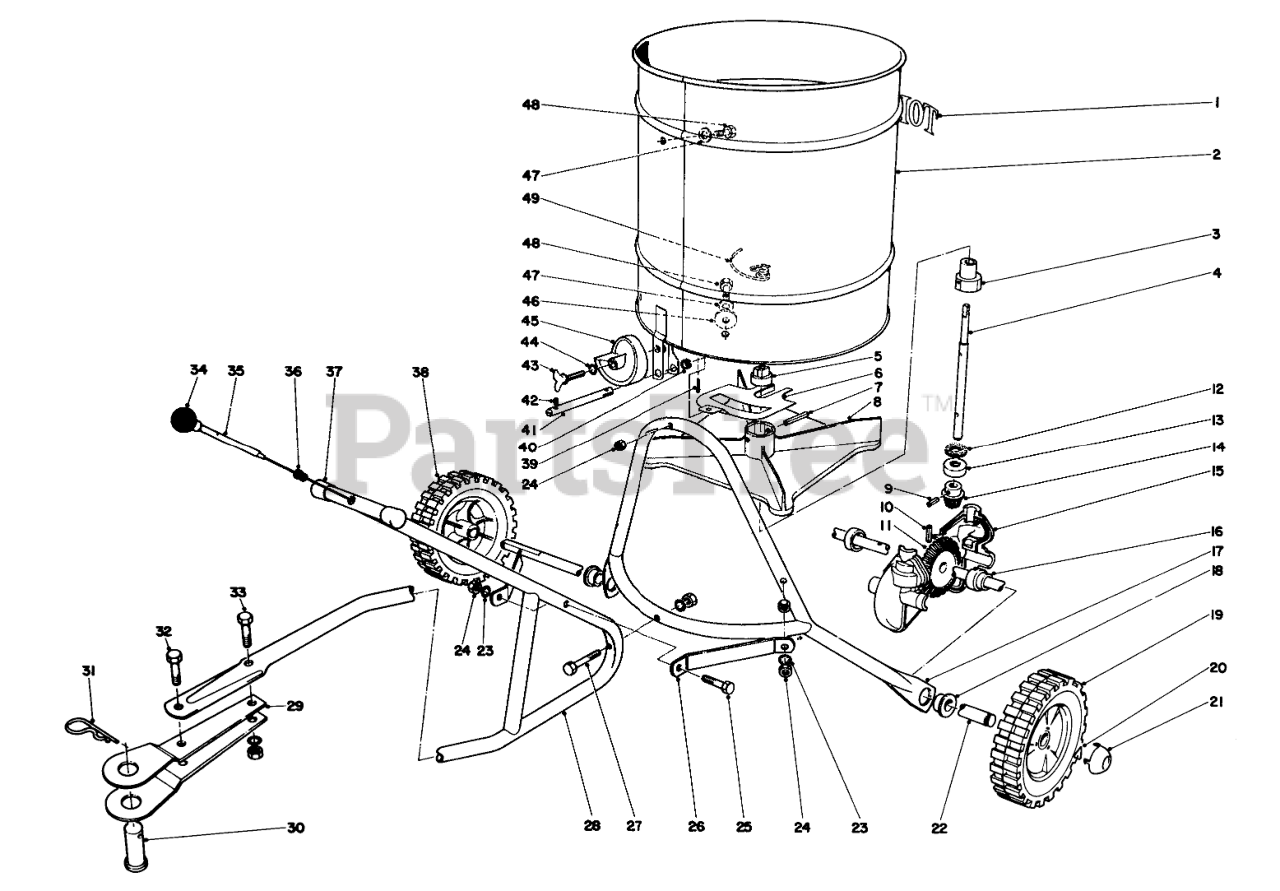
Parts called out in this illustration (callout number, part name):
1	Decal
2	Hopper
3	Nylon cam
4	Fan shaft
5	Bearing
6	Discharge plate
7	1/8 X 1-3/8 ROLL PIN
9	PIN-SPRING
10	PIN-SPRING
11	Gear, axle
12	Felt washer
14	Pinion
15	Gear case
16	Slotted cap
17	Frame
18	Axle bearing
19	Wheel
20	Retainer, wheel
21	Hub cap
22	Axle shaft
23	WASHER-LOCK, INTERNAL
24	NUT-HEX
25	SCREW-HH
27	SCREW-HH
28	Tow bar
29	Hitch plate
30	Pin
31	PIN-HAIR
32	SCREW-HH
33	SCREW-HH
35	Control wire
36	Spring
37	Plastic caps
38	Drive wheel
39	PIN-COTTER
40	Bearing
41	Rate control rod
42	Set screw
43	Special bolt
44	WASHER-LOCK
45	Dial indicator
46	Washer
47	WASHER-FLAT
48	SCREW-HH
49	Agitator
